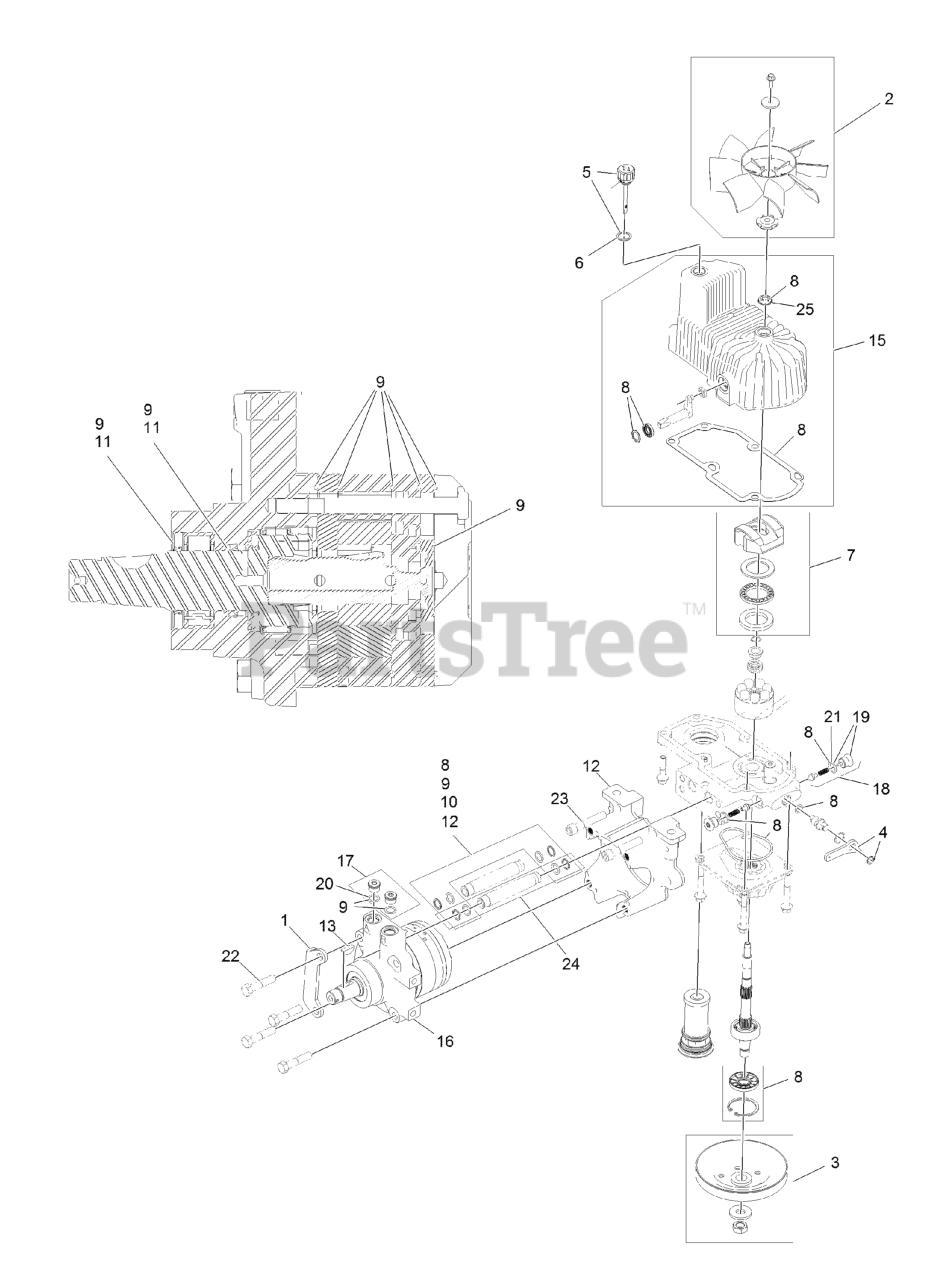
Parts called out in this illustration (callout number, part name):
1	MOUNT-SHOE, HORSE
2	FAN KIT
3	PULLEY KIT
4	HANDLE-BYPASS VALVE, HYDRO
5	DIPSTICK-HYDRO W/GASKET
6	GASKET-DIPSTICK, HYDRO
7	SWASH BLOCK KIT
8	PUMP SEAL KIT
9	MOTOR SEAL KIT
10	TUBE SEAL KIT
11	OUTPUT SHAFT SEAL KIT
12	NOSE CUP-UHT
13	KEY-WOODRUFF
15	HOUSING-HYDRO, RH
16	MOTOR-HYDRAULIC RH 240CC
17	MAGNETIC PLUGS SERVICE KIT
18	CHECK VALVE ASM
19	PLUG-CHECK (W/O-RING)
21	O-RING-CHECK VALVE
22	SCREW HH
23	SCREW-HSH
24	HYDRAULIC TUBE KIT
25	SEAL-FAN DRIVE
